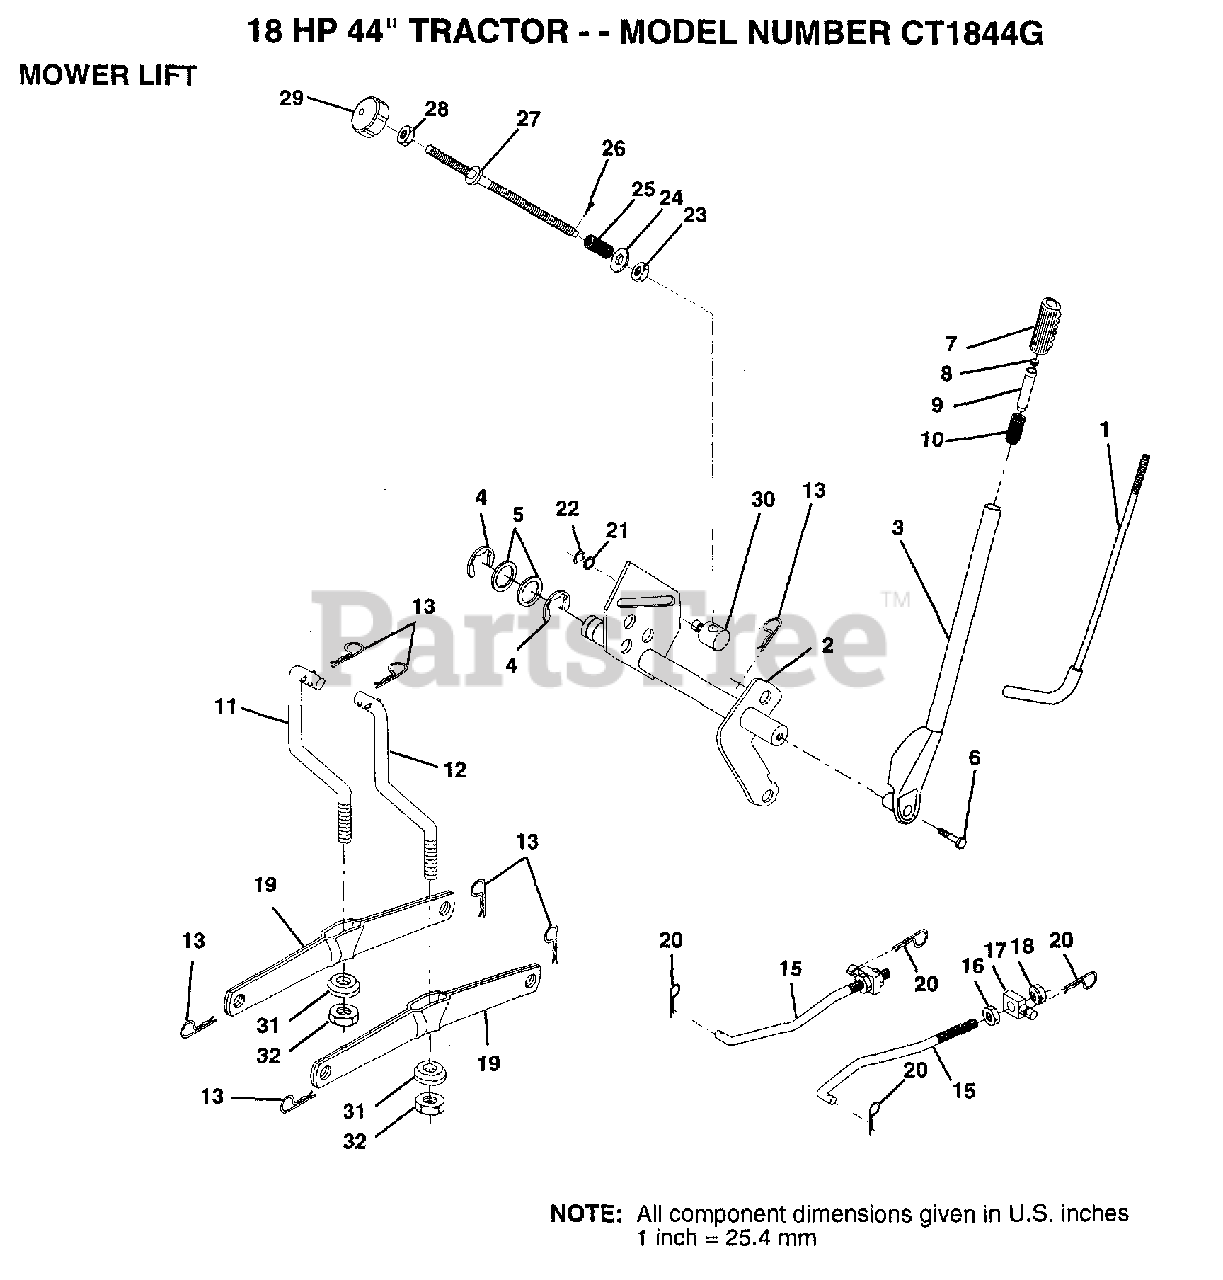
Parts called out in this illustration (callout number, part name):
1	LEVER ROD LT
2	SHAFT LIFT W/IND
4	E-RING
5	WASHER
6	"BOLT,HEX"
7	GRIP
10	SPRING T
11	LINK LIFT LH
12	LINK LIFT RH
15	LINK.FRONT
16	NUT
17	TRUNION
18	NUT.LK.W/WSH.1/2.
19	ARM SUSP REAR
20	RETAINER.SPRING
21	WASHER
22	KLIP RING
23	NUT T
24	WASHER
25	SPRING T
27	ROD LIFT LT
28	NUT
29	KNOB INF 3/8-16
30	TRUNION LT
31	BEARING PVT LH
32	NUT.LOCK.3/8-24
